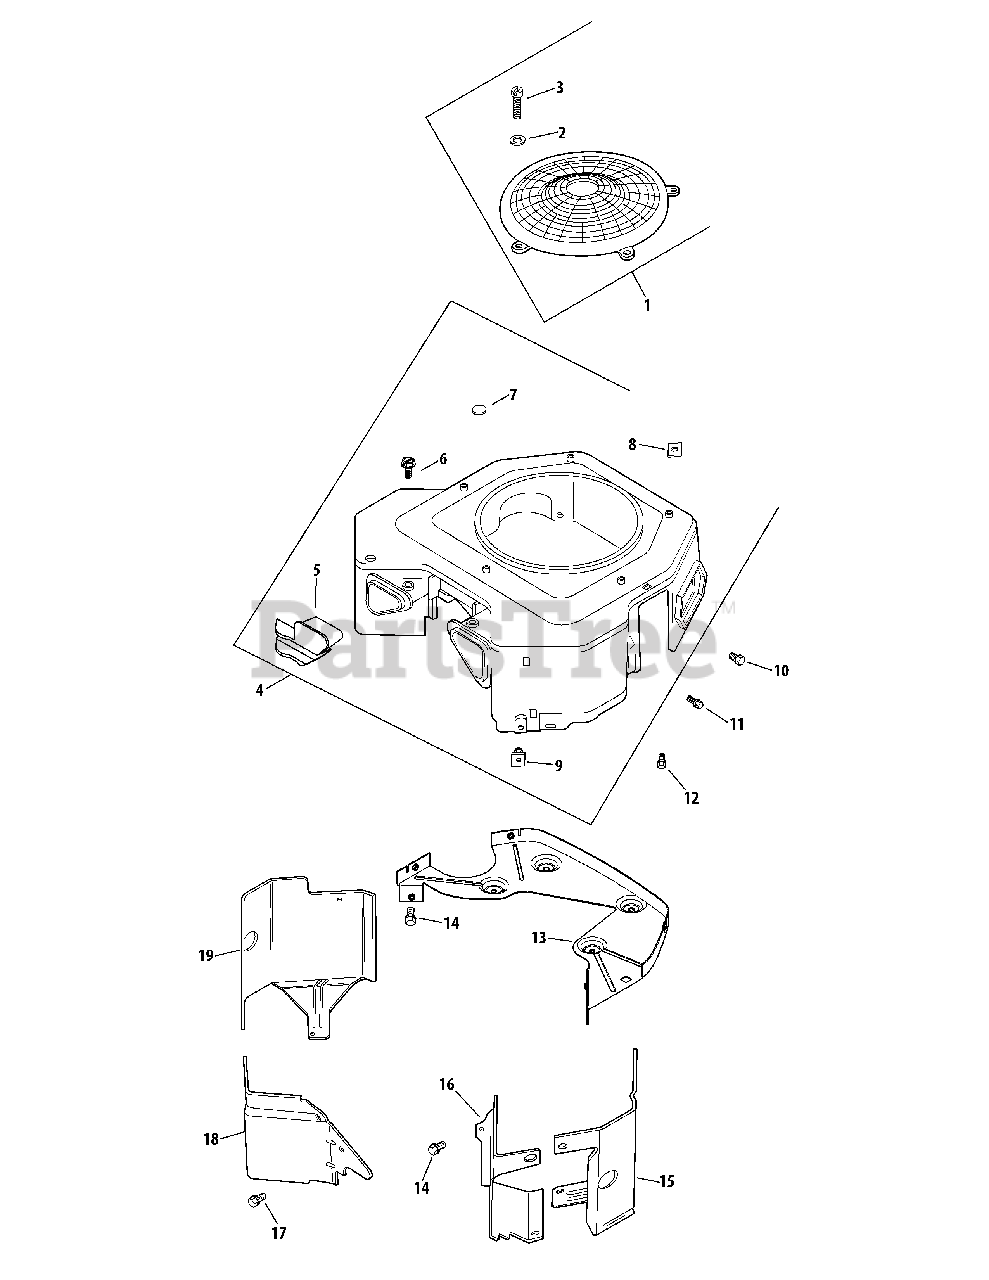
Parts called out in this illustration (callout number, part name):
1	Fixed Guard Kit
2	Flat Washer, 7/32
3	Pan Screw, M5 x 0.8 x 10
4	Blower Housing Kit (Inc. 5-9 & KH-24-332-01-S)
5	Blower Housing Cover
6	Washer Screw, #8-18 X 1/2
7	Button Plug, 9/16
10	Thread Forming Void Screw
11	Flange Screw, M5 x 0.8 x 16
12	Flange Screw, M5x.8X20
13	Backing Plate
14	Flange Screw, M6 x 1.0 x 16
16	Valley Baffle, #2
17	Flange Screw, M5 x .8 X 10
18	Valley Baffle, #1
